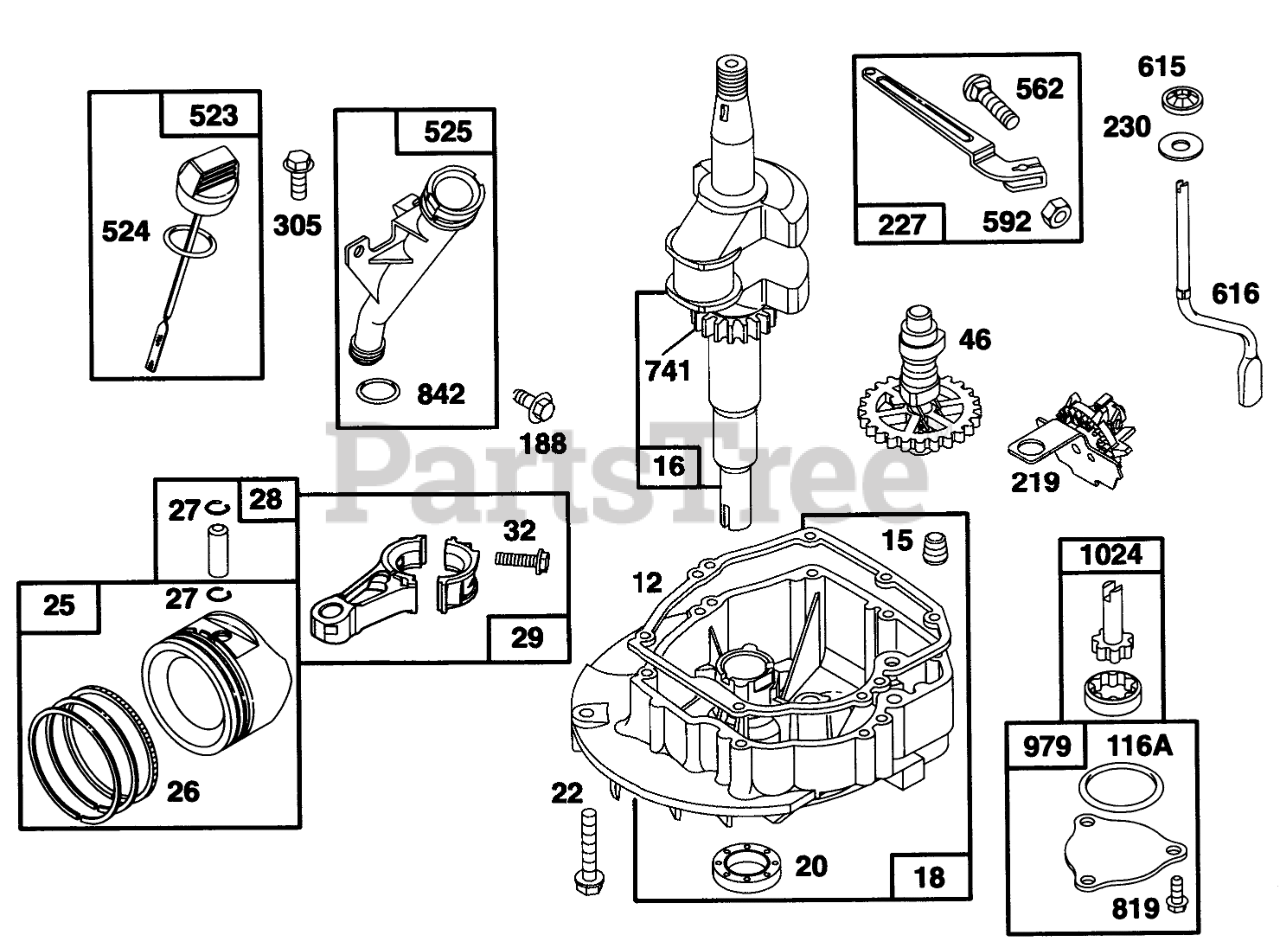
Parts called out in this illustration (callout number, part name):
12	ENGINE BASE GASKET
15	PIPE PLUG
16	CRANKSHAFT
18	ENGINE SUMP
20	SEAL-OIL
22	SCREW - ENGINE BASE
25	STD PISTON ASSEMBLY
26	STD RING SET
27	PISTON PIN LOCK
28	PIN ASM - PISTON
29	CONNECTING ROD
32	Connecting Rod
37	GUARD - FLYWHEEL
46	CAM GEAR
116A	O RING SEAL
188	Screw-Cap
219	GOVERNOR/OIL SLINGER
227	GOVERNOR LEVER ASSEMBLY
230	WASHER
305	SCREW - HEX HEAD
523	DIPSTICK-OIL
524	O-RING
525	OIL FILLER TUBE
562	GOVERNOR LEVER BOLT
592	HEX NUT
615	FASTENER
616	GOVERNOR CRANK
741	TIMING GEAR
819	SCREW - SEM
842	O-RING
979	OIL PUMP COVER
1024	OIL PUMP
